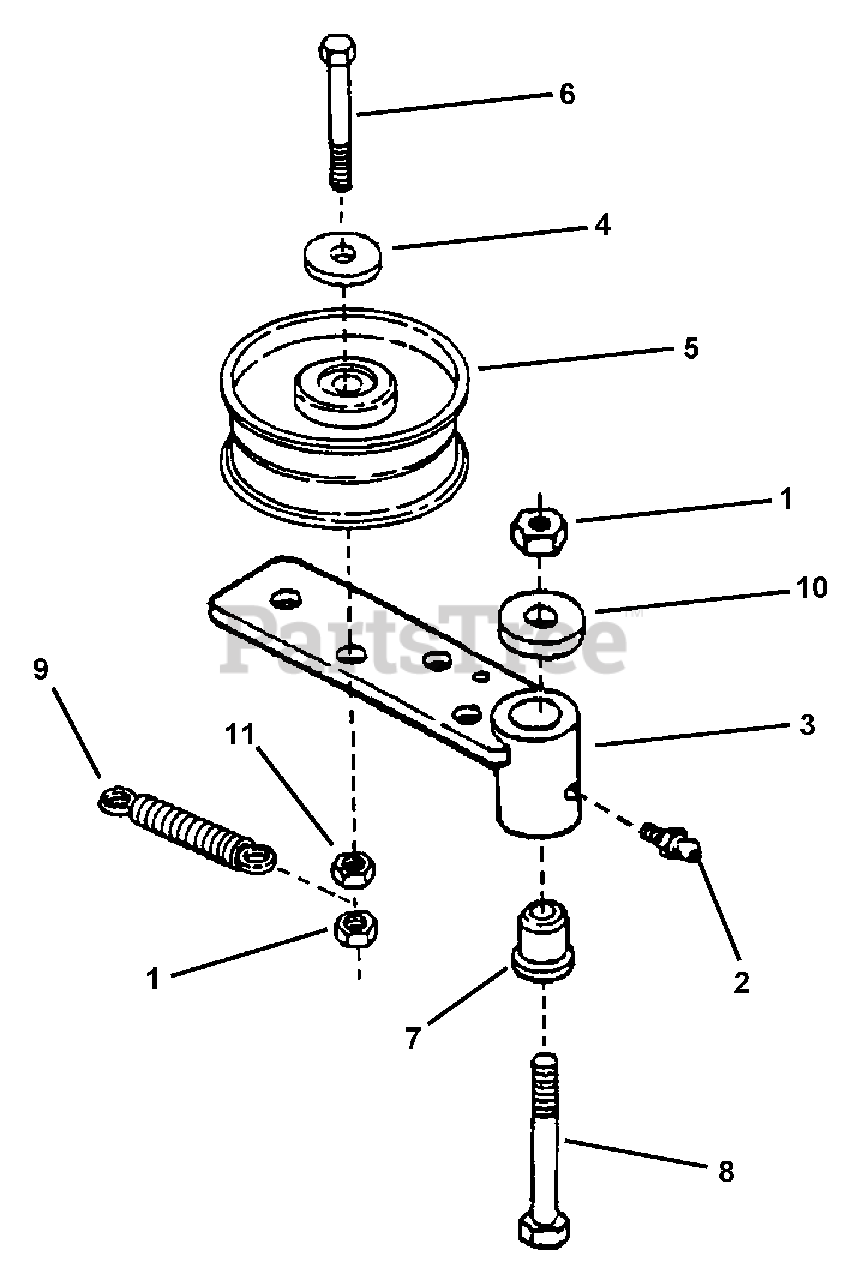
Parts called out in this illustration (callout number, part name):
1	NUT, 3/8-16, HEX TOP LOCK
2	FITTING, 1/4-28 Lube
3	IDLER Weldment
4	WASHER, 3/8" USS
5	PULLEY, Idler
6	BOLT, 3/8-16 x 3-1/4", Grade 5
7	SPACER, Pivot
8	BOLT, 3/8-16 x 3-1/2", Grade 5
9	SPRING, Idler Tension
10	BUSHING, 14 GA Spacer
11	NUT, 3/8-16
